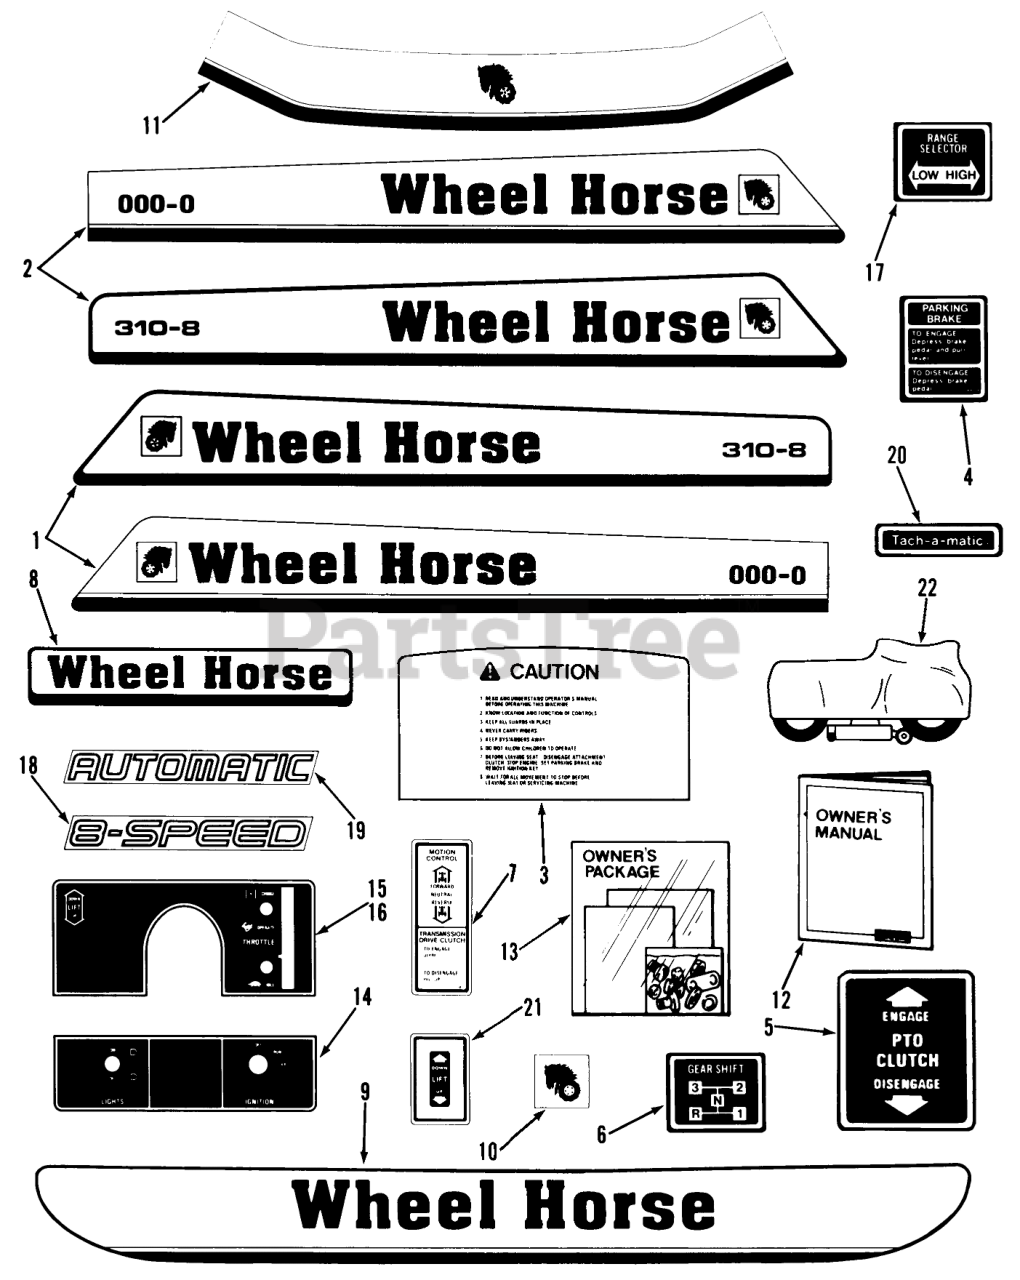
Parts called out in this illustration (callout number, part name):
1	RH DECAL HOOD
4	DECAL-PARKING BRAKE
7	DECAL SPD CONTROL
12	Owners Manual-Tractor
17	DECAL, RANGE SELECTOR
